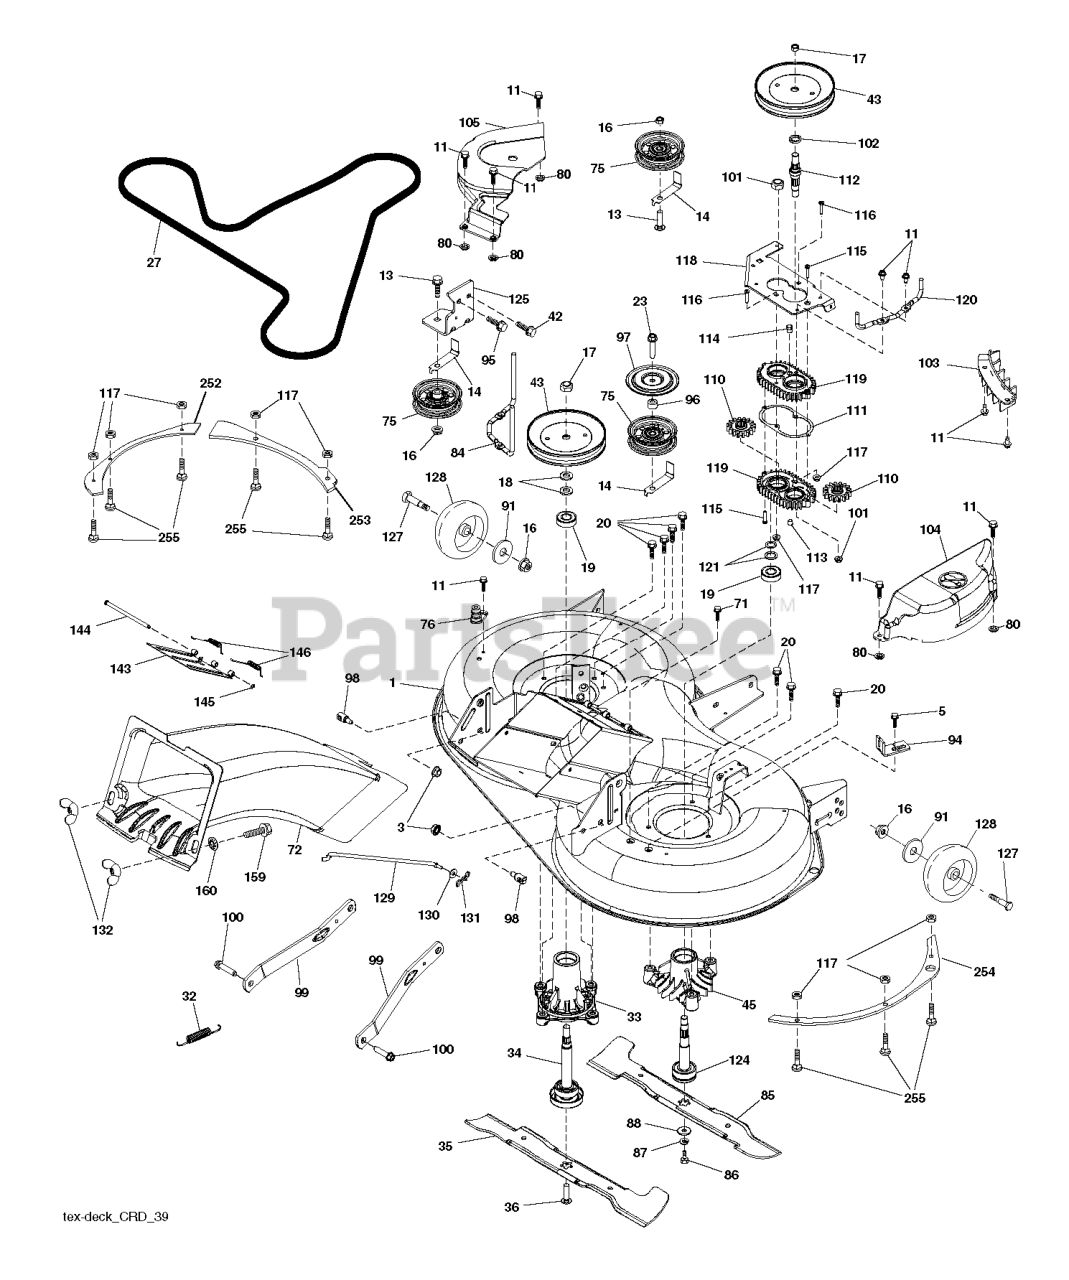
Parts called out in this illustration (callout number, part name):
1	DECK.SVC.WLDT.97EL.TCRD.EZ.498
3	NUT LOCK HEX FLANGE 5/16-18
5	BOLT.5/16HEX.WHS.HD
11	SCREW.1/4-20X5/8
13	BOLT.3/8-16X1.50
14	KEEPER, BELT IDLER
16	NUT LOCK FLG 3/8-16 UNC
17	NUT.FLANGE.LOCK.TOP
18	WASHER.SPACER.MANDREL
20	SCREW, WASHER HEAD
23	SCREW LT
27	BELT 97CM ELECTRIC
32	SPRING 107CM & 97CM ELECTRIC D
33	RP.HOUSING.MANDREL.4PT.
34	SHAFT.ASM.MDRL.N/GREASE.38
35	BLADE.3N1.LH.CRD.97
36	BOLT.WASHER.ASM.7/16-2
42	SCREW
43	PULLEY.MANDREL.5.0.PD.38"
45	HOUSING.MANDREL.44/46" VENT
71	SCREW 3/8-16X1/2
72	CHUTE REAR CRD UPPER CHUTE TEX
75	FLAT IDLER PULLEY
76	PORT.WASHOUT
80	PALNUT 1/4
84	BELT KEEPER.MANDREL.38"COATED
85	BLADE.3N1.RH.CRD.97
86	BOLT.3/8-24X1.25GR8. LHTHRD
87	LOCKWASHER
88	WASHER.BLADE
91	WASHER
94	BRKT.CLUTCH.CABLE
95	SCREW, 3/8-16X3/4
96	SPACER
97	PROTECTOR
98	STUD.FASTNER.W/ANTI-ROTATE
99	ARM.SUSPENSION.MOWER.R
100	BOLT.SHOULDER
101	NUT.CROWNLOCK.9/16 -18.UNC
102	SPACER BEARING
103	GUARD GUARD FRONT VENT
104	97.CRD.RH.MANDREL.COVER
105	MANDREL MANDREL COVER LH
110	CRD.SPUR.GEAR
111	GASKET GASKET GEARCASE
112	SHAFT SHAFT. CRD GEARCASE ADAP
113	PLUG PLUG OIL
114	VALVE VALVE RELIEF
115	SCREW
116	BOLT.CARIGE.SS.1/4-20X1.75GR5
117	NUT T
118	ARM ARM CLUTCHING
119	GEARCASE GEARCASE SUBASM
120	BRACKET KEEPER BELT RH
121	WASHER WASHER
124	MANDREL SHAFT NON/GREASE
125	BRACKET BRACKET IDLER CHASSES
127	BOLT.SHOULDER.3/8-16X3-5/8.
128	RP WHEEL. GUAGE RALLY
129	ROD.ANTI.SWAY.48/54"K4
130	WASHER
131	PIN.COTTER.5/16.BOW TI
132	KNOB.HANDLE.3/8.TRI-POINT.BLAC
143	DOOR
144	PIN PIN.HINGE
145	E-RING.5/16"
146	SPRING SPRING: EZ MULCH DOOR
159	BOLT
252	PLATE 97 LEFT BOLT REINFORCING
253	PLATE 97 LH SIDE BOLT ON
254	PLATE 97 RH SIDE BOLT ON
255	RHSNB, 1/4-20 X 1, GR5
